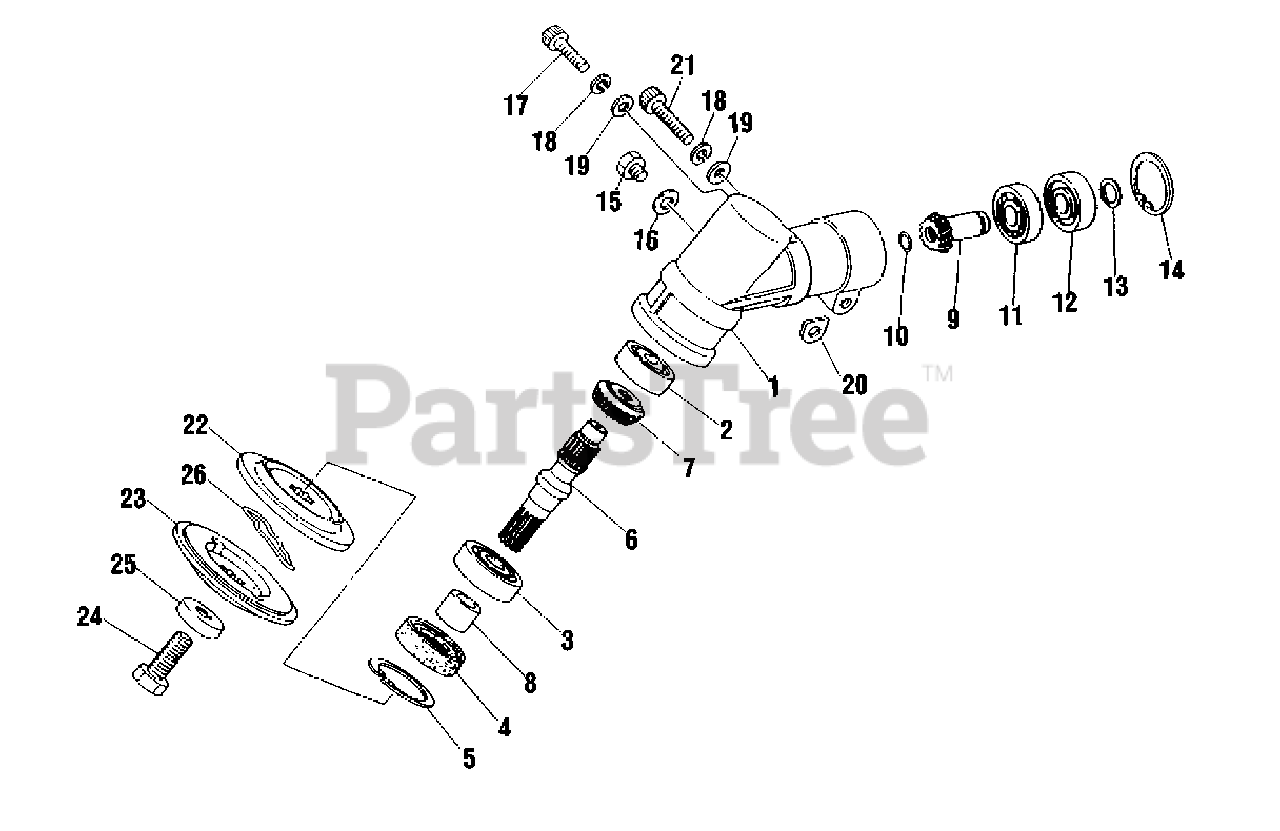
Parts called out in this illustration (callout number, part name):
1	CASE, GEAR
2	BEARING, BALL - 6000DDU
3	BEARING, BALL - 6202
4	SEAL, OIL
5	RING, RETAINING - 35
6	GEAR - SHAFT
7	GEAR - BEVEL
8	COLLAR
9	GEAR - BEVEL
10	RING, RETAINING
11	BEARING, BALL - 6001
12	BEARING, BALL - 6001ZZ
13	RING, RETAINING
14	RING, RETAINING - 28
15	BOLT - 6X10
16	WASHER
17	SCREW - 6X12
18	LOCKWASHER - 6
19	WASHER - 6
20	SHIM
21	SCREW - 6X28
22	HOLDER (A)
23	HOLDER (B)
24	BOLT - 10 -- LEFT HAND
25	GUARD
26	SLIDE PIN
